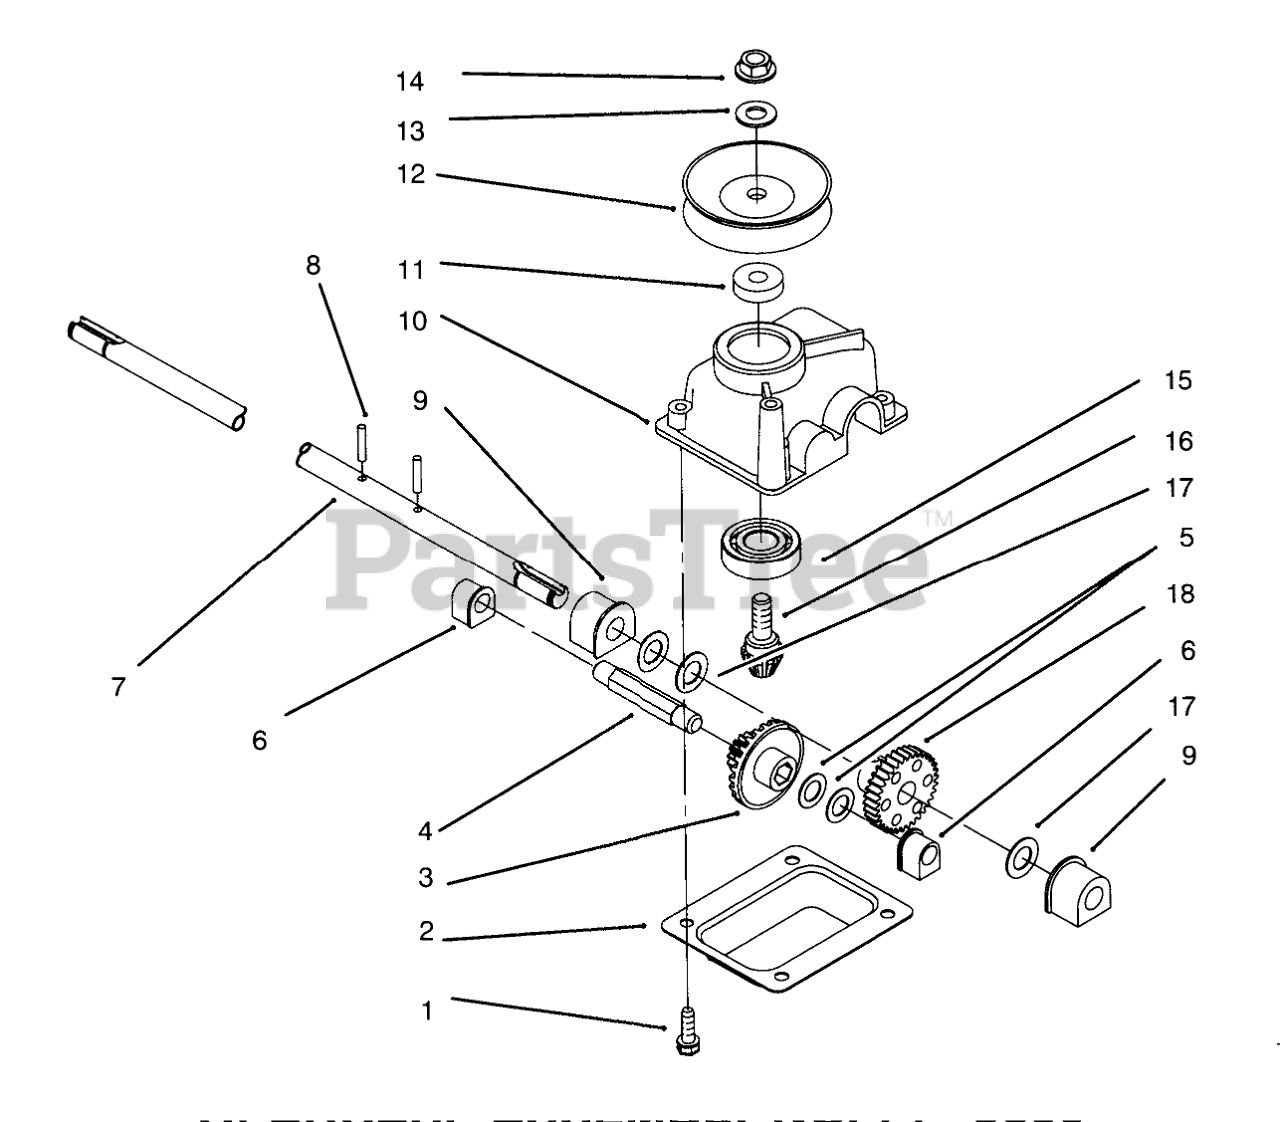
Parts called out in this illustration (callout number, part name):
1	SCREW-HWHTF
2	Cover-Gear Case
3	Gear-Bevel
4	SHAFT-INTERMEDIATE
5	WASHER-THRUST
6	BUSHING
7	OUTPUT SHAFT
8	5/32 X 7/8 ROLL PIN
9	BUSHING
10	GEARCASE
11	SPACER
12	PULLEY-DRIVEN HALF
13	WASHER-FLAT
14	NUT-HEX
15	BEARING-BALL
16	Gear-Pinion
17	WASHER-PLAIN
